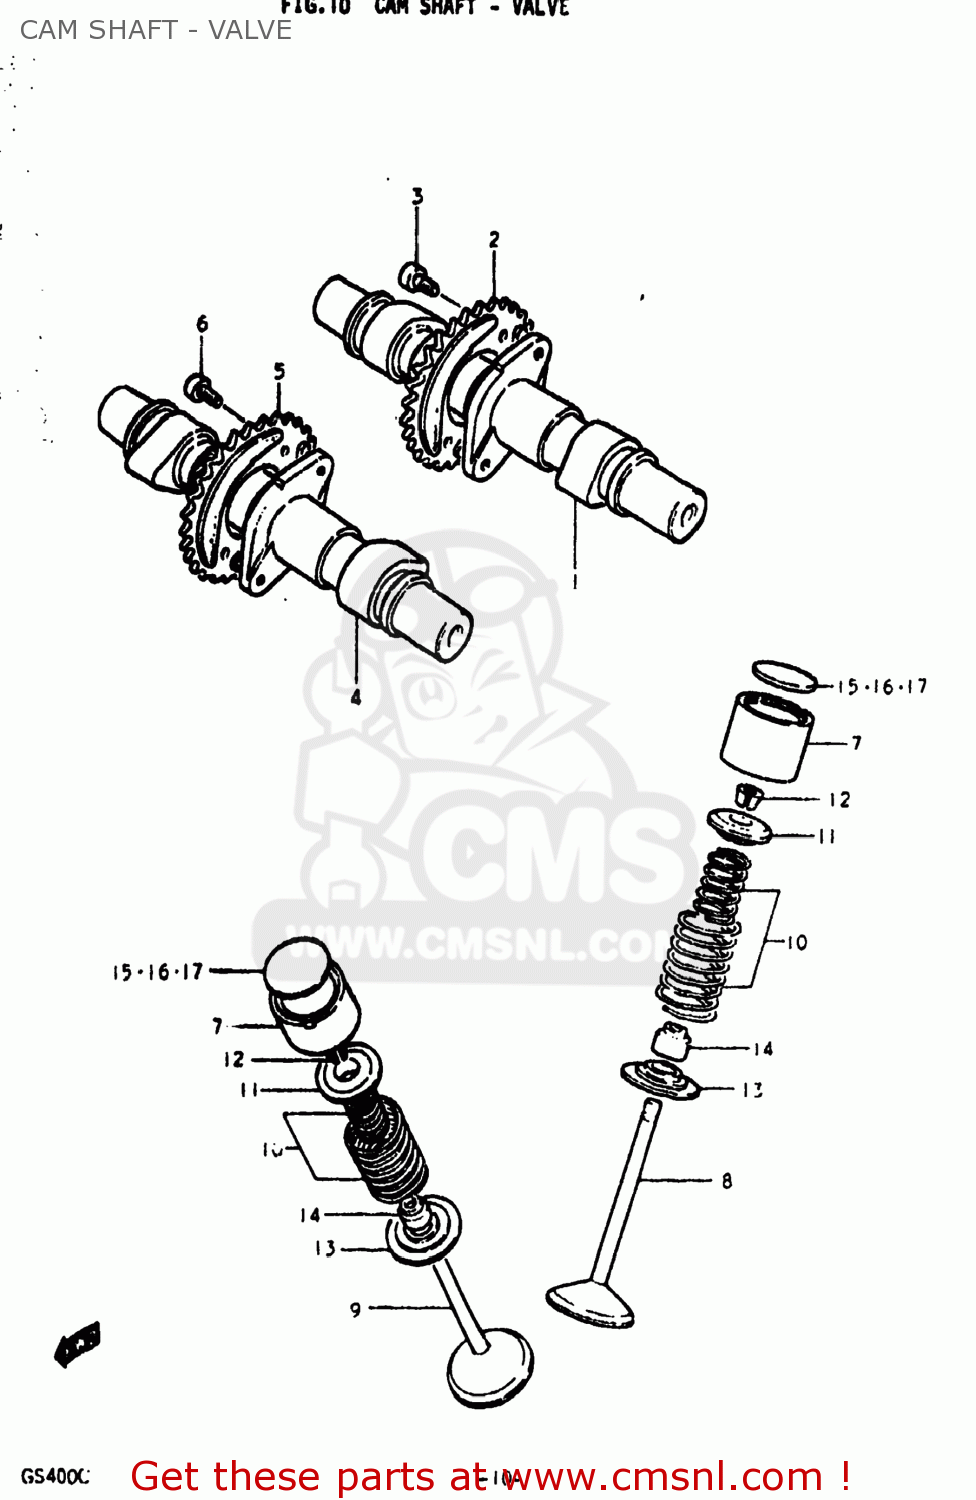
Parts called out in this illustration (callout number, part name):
1	CAMSHAFT
2	SPROCKET,CAMSHAFT
3	BOLT 6X11
4	CAMSHAFT,EXHAUST
5	SPROCKET,EXHAUST CAMSHAFT
6	BOLT 6X11
7	TAPPET
8	VALVE,INTAKE
9	VALVE,EXHAUST
10	SPRING SET,VALVE
11	RETAINER,VALVE SPRING
12	COTTER,VALVE
13	SEAT,VALVE SPRING
14	SEAL,OIL(7X14.4X9)
15	SHIM,TAPPET
16	SHIM,TAPPET
17	SHIM,TAPPET
18	SHIM SET,TAPPET
19	CASE
